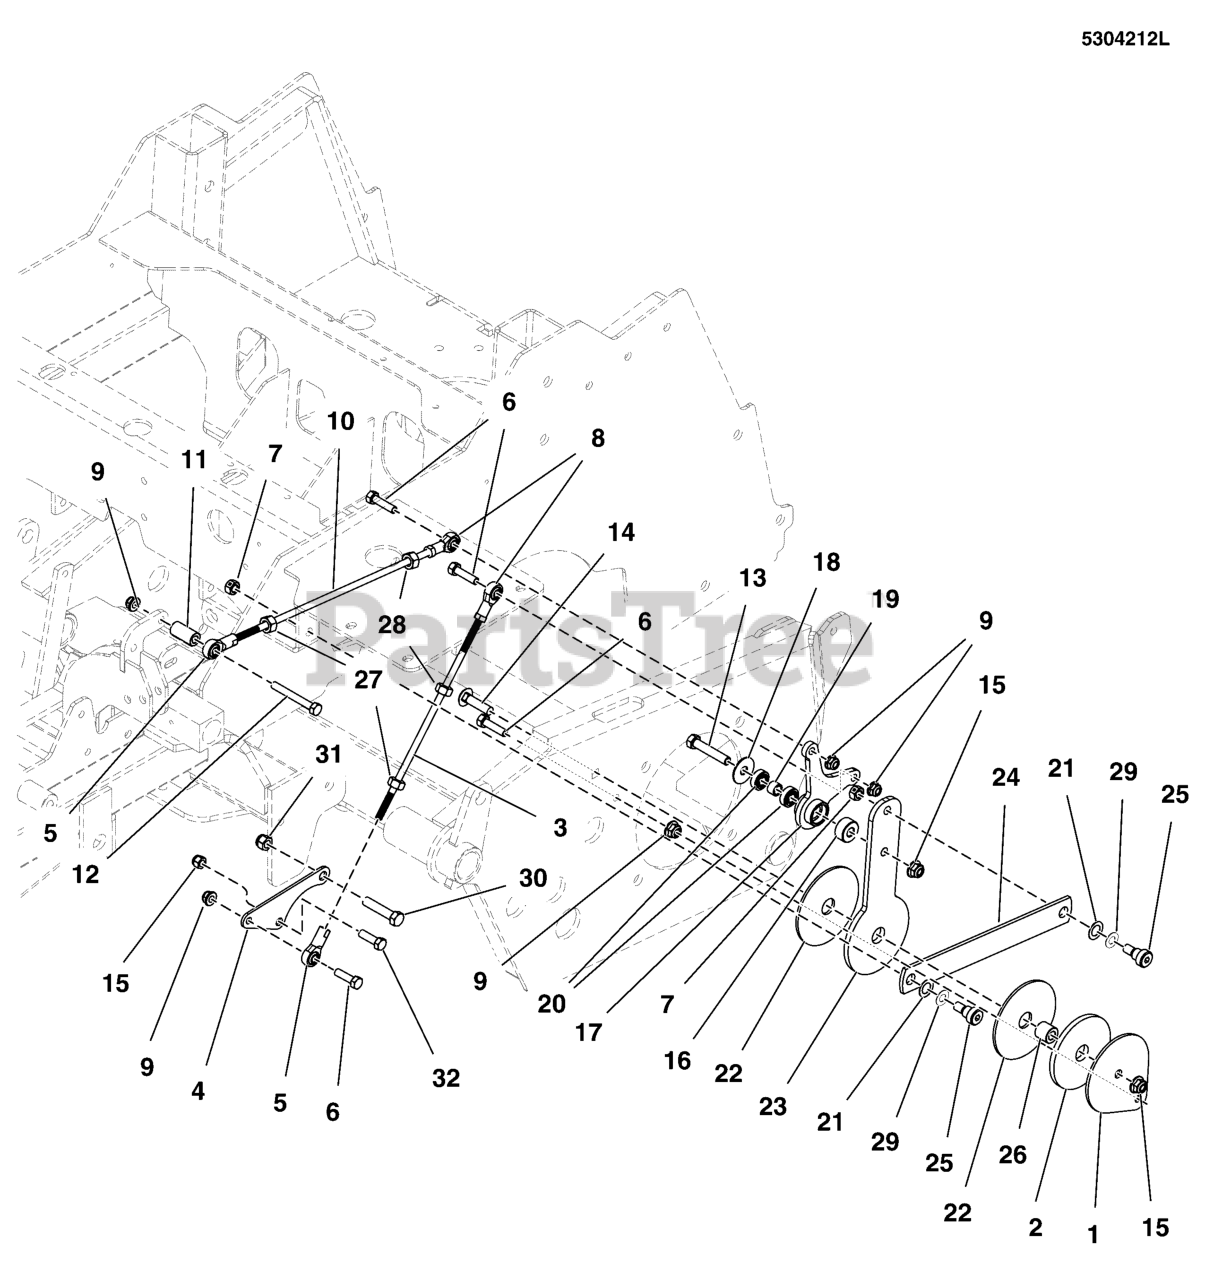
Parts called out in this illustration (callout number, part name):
1	PLATE, CONTROL SYSTEM LOCK - BLK
2	PAD, .77 X 3.50 X .25, POLYURETHANE
3	ROD, 5/16-24 RH & LH, 8.75" CZ
4	PLATE, CONTROL MOUNT - BLK
5	BALL JOINT 5/16-24 RH FEMALE BRONZE RACE
6	BOLT, 5/16-18 X 1-1/4 GD5 TFL, CZ
7	NUT, Hex, Side Lock, 3/8-16
8	BALL JOINT 5/16-24 LH FEMALE BRONZE RACE
9	NUT, 5/16-18 HEX NYLOCK FLANGE NUT
10	ROD, HYDR LINKAGE, 18.00
11	SPACER, .38 X .75 X 1.25, PM, CZ
12	BOLT, 5/16-18 X 2-1/2" GD5 YZ
13	BOLT, 3/8-16 X 2-1/2" GD5 CZ
14	BOLT, 3/8-16 X 1-1/2, CARRIAGE, GD5, CZ
15	NUT, 3/8 - 16 HEX NYLOCK FLANGE
16	SPACER, .39 X 1.00 X .50, PM, CZ
17	PIVOT, CONTROL SYSTEM, S125XT
18	WASHER, 3/8" Fender
19	SPACER, .39 X .55 X .38, PM, CZ
20	BEARING, .375" ID X .875" OD X .341" THK
21	WAVE WASHER, 1/2"ID X 087"OD X .01 THK.
22	PAD, CONTROL SYSTEM
23	PLATE, CONTROL SYSTEM ARM - HT
24	LINK, CONTROL SYSTEM ARM, IS2100 - BLK
25	BOLT, 3/8-16 X 3/8", 1/2" SHOULDER
26	SPACER, .39 X .75 X .69, PM, CZ
27	NUT, Hex, 5/16-24
28	NUT, 5/16-24 HEX, LH
29	WASHER, 1/2" GD9 YZ
30	BOLT, 7/16-14 X 3/4, GD 5 YZ
31	NUT, 7/16-14 HEX TOP LOCK
32	BOLT, 3/8-16 X 1" GD5 CZ
